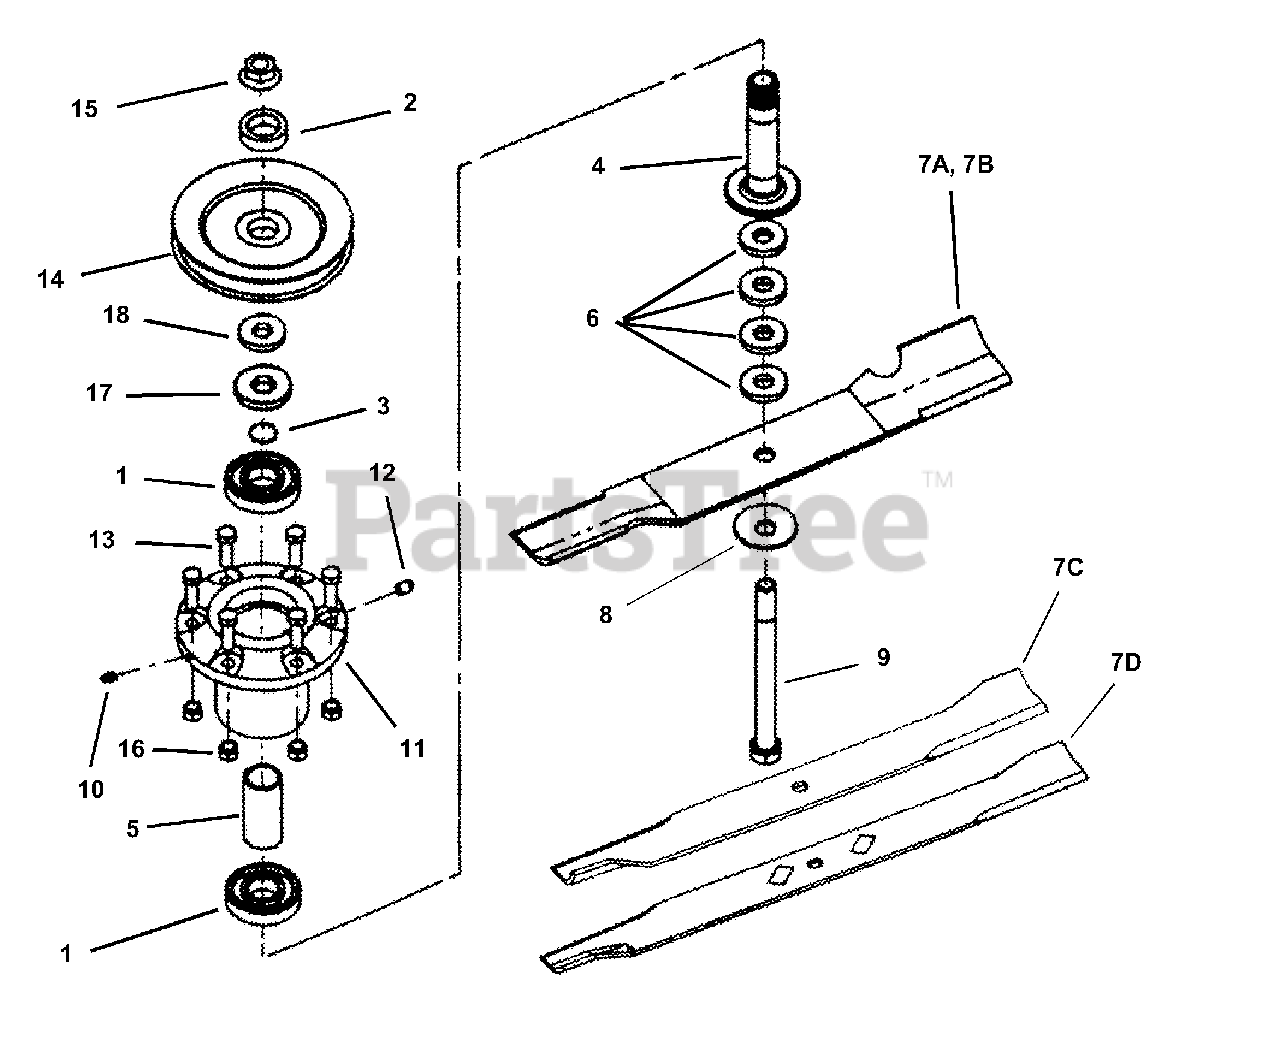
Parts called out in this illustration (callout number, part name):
1	BEARING, Sealed
2	WASHER, Spindle
3	SNAP-RING, Spindle Shaft
4	SHAFT, Spindle
5	SPACER, Bearing
6	SPACER, Blade
7A	BLADE, 21" (61" Deck) (High Lift)
7B	BLADE, 18" (52" Deck)
7C	BLADE, 21" (61" Deck) (Low Lift)
7D	BLADE, 25" (73" Deck)
8	WASHER, Beveled
9	BOLT, 5/8-18 x 7-1/2" Hex Head Cap, Grade 5
10	LUBE FITTING, 1/4-28 Thread Forming
11	HOUSING, Cutter
12	VENT, Spindle
13	BOLT, 3/8-16 x 1-1/4" Rib Necked
14	PULLEY, 5-3/4" O.D. (61" Deck)
15	NUT, 5/8-18 Hex Flange Lock, Grade 5
16	NUT, 3/8-16 HEX NYLON LOCK
17	SEAL, Nylos
18	WASHER
